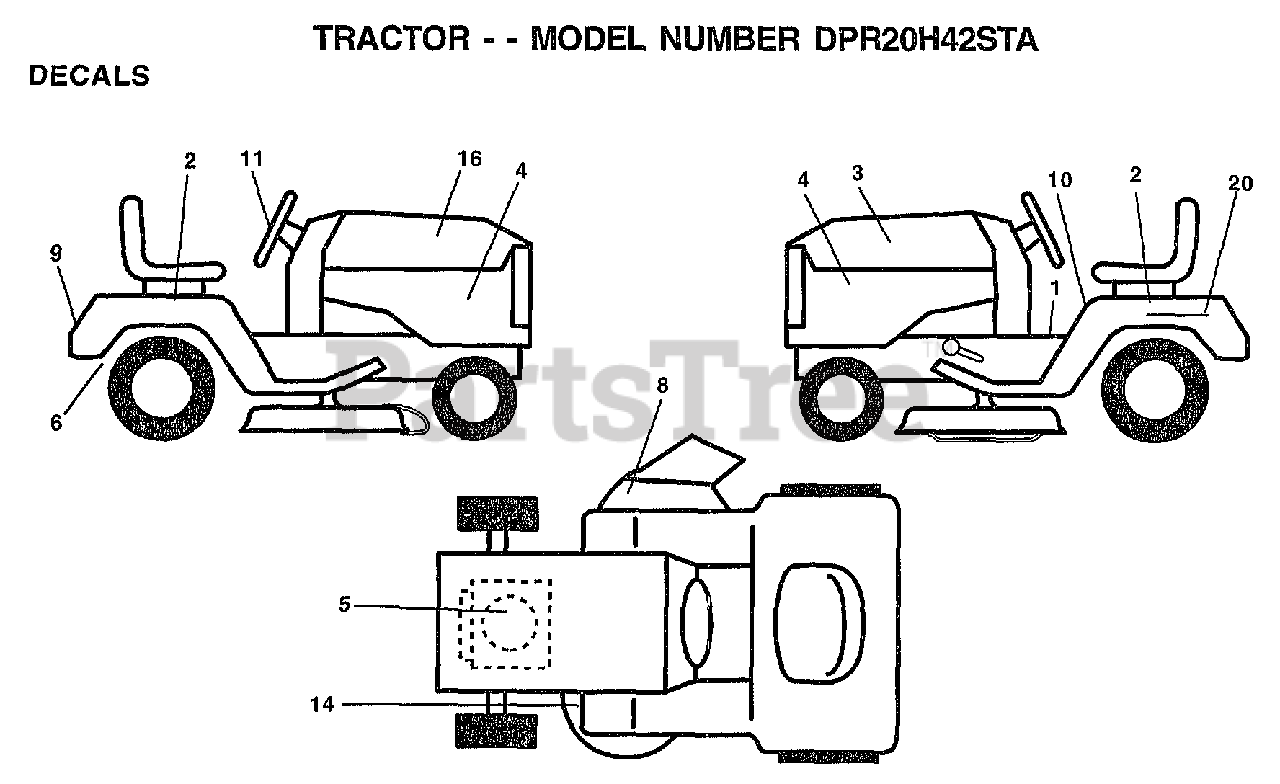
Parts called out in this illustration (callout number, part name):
1	"DECAL FENDER,OPER"
2	DECAL
4	DECAL
6	DECAL BY PASS LT HYDRO
8	DECAL
9	DECAL
10	DECAL.CAUT.ENG/FR
11	DECAL
14	"DECAL-SCHEM,BELT"
20	DECAL.BATRY.3-3908
